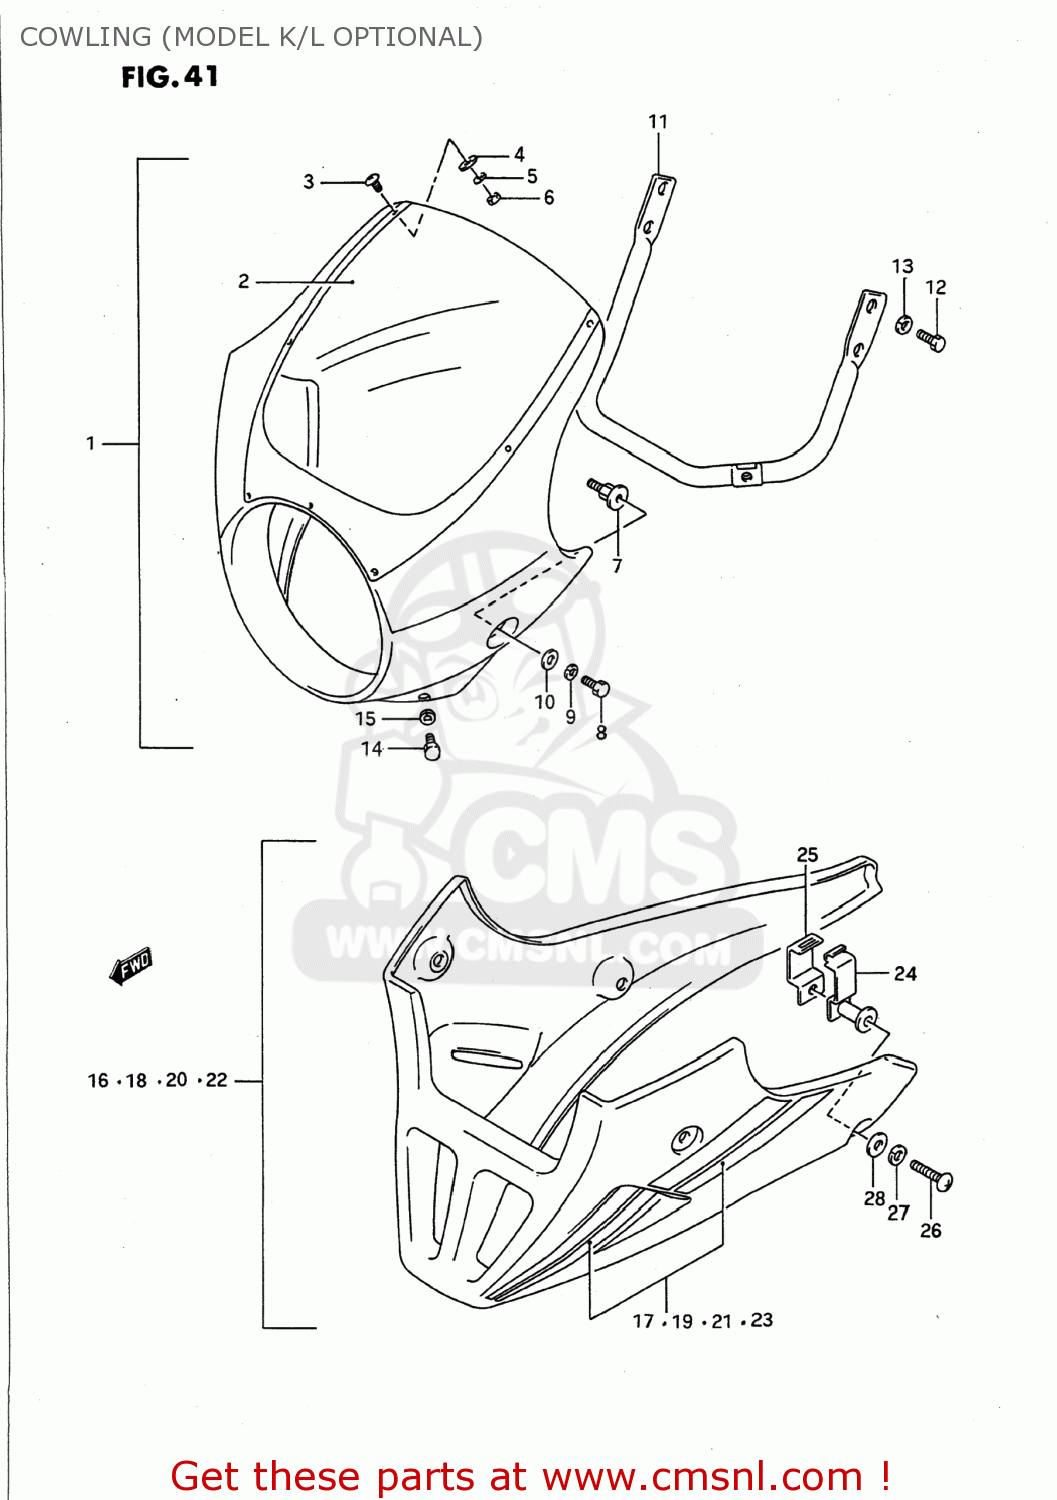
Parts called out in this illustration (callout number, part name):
1	COVER SET,UPPER COWLING
2	SCREEN
3	SCREW
4	WASHER
5	LOCK WASHER
6	NUT
7	BOLT,COWLING HEADLAMP
8	BOLT
9	WASHER,LOCK
10	WASHER
11	BRACE,UPPER COWLING
12	BOLT
13	WASHER
14	BOLT
15	WASHER,LOCK
16	COWLING ASSY,UNDER (RED)
17	TAPE SET,UNDER COWLING
18	COVER SET,UNDER COWLING (W
19	TAPE SET,UNDER COWLING
20	COVER SET,UNDER COWLING (R
21	TAPE SET,UNDER COWLING
22	COVER SET,UNDER COWLING (B
23	TAPE SET,UNDER COWLING
24	BRACKET,UNDER COWLING OUTER
25	BRACKET,UNDER COWLING INNER
26	SCREW
27	WASHER,LOCK
28	WASHER
